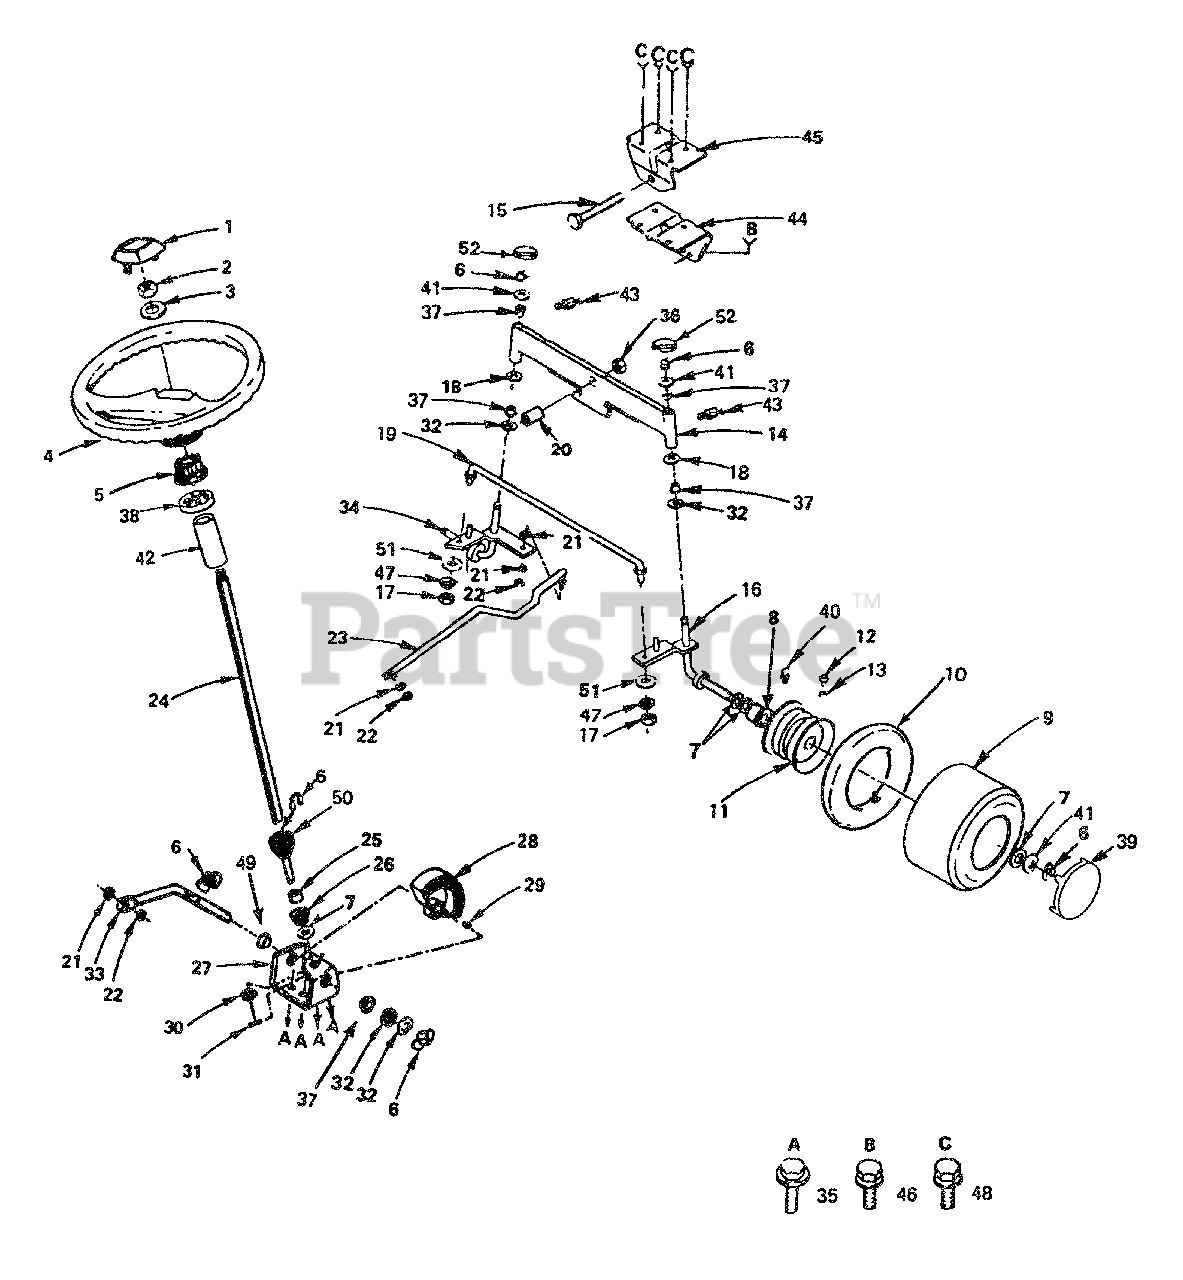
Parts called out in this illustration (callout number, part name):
1	Insert-Steering Wheel
2	Hex Toplock Jam 1/2-20
3	Washer 17/32 x 2-1/4 x .160
4	Steering Wheel
5	Adapter-Wheel, Steering
7	Washer 25/32 x 1-1/4 x 16 Ga.
8	Bearings Wheel, Front
9	Tire-Rib Tread (Tubeless)
10	Tube-Tire
11	Rim Assembly 6" Front
12	Stem-Valve
14	Axle Assembly-Front
15	Bolt-Hex 5/8-11 x 3-3/4
16	Spindle Assembly-R.H.
17	Nut-Hex 5/16-24
18	Washer 27/32 x 1-1 /4 x 16 Ga.
19	Tie Rod
20	Bearing
21	Lockwasher 3/8
22	Nut-Hex 3/8-24
24	Shaft Assembly-Steering
26	Bushing-Steering Rod
27	Bracket Assembly-Steering
28	Gear-Sector
29	Woodruff Key 3/16 x 3/4
30	Washer, hardened
31	Drive Pin 3/16 x 1
32	Bearing, Thrust
33	Rod-Steering
34	Spindle Assembly-L.H.
35	Screw-Hex Washer Hd. Thread Forming Type TT 3/8-16 x 3/4
36	Nut-Lock Flange, 5/8-11
38	Spacer, Shaft Steering
39	Cover, Wheel 6"
40	Grease Fitting
41	Washer 25/32 x 1-5/8 x 16 Ga.
42	Tube, Shaft Steering
43	Fitting, Grease
44	Support-Saddle, Front
45	Support-Saddle, Rear
46	Screw-Hex Washer Thd. Rolling 5/6-18 x 12
47	Lockwasher 5/16
48	Screw-Special
49	Nylinder, Snap In
50	Gear-Pinion
51	Washer 11/32 x 3/4 x 16 Ga.
52	Spindle Cap
